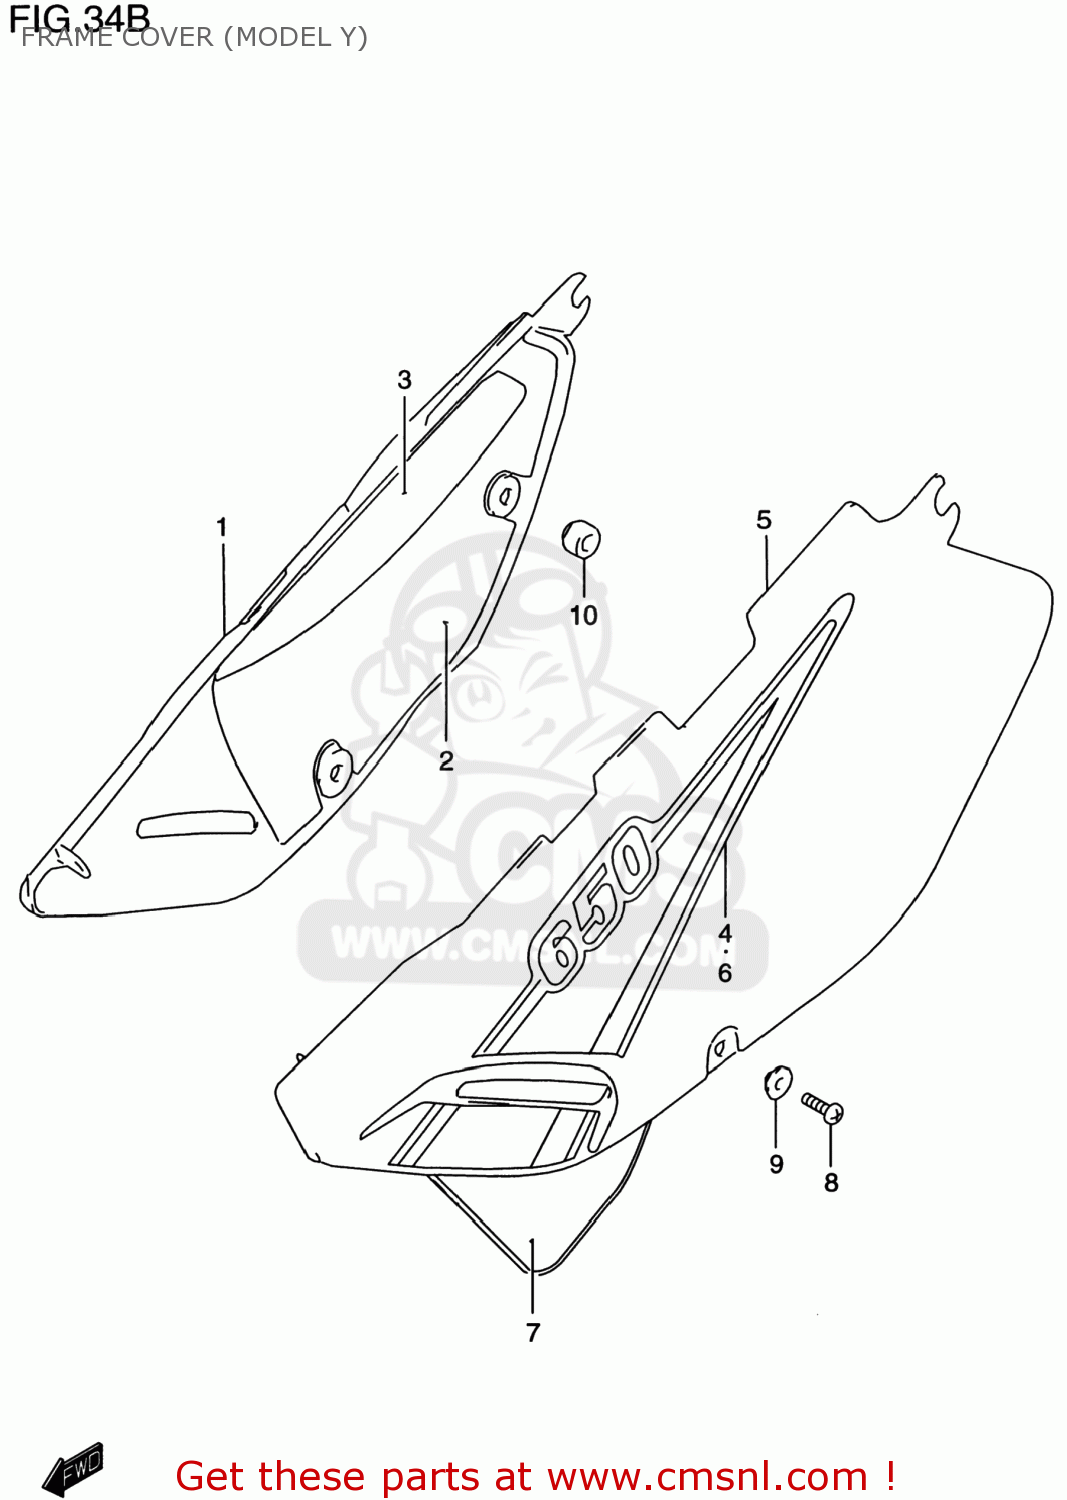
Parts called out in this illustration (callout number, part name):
1	COVER,FRAME,RIGHT
2	SHIELD,FRAME COVER,R NO.1
3	SHIELD,FRAME COVER,R NO.2
4	TAPE,FRAME COVER,R
5	COVER,FRAME,LEFT
6	TAPE,FRAME COVER,L
7	TAPE,LWR
8	SCREW
9	WASHER
10	CUSHION
